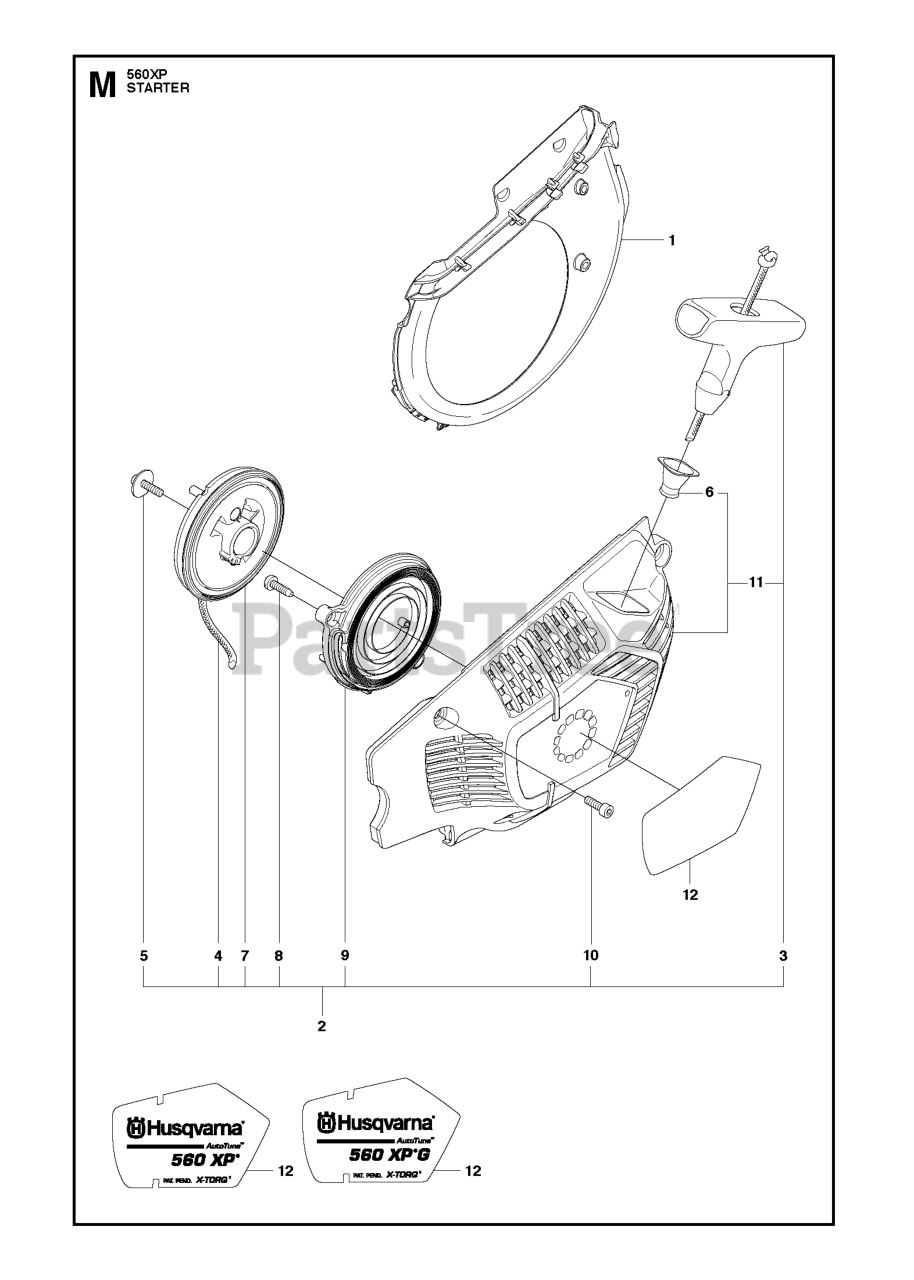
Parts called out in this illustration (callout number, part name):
1	COOLING AIR CONDUCTOR
2	STARTER ASSY
3	HANDLE
4	STARTER ROPE
5	SCREW
6	SLEEVE
7	STARTER PULLEY ASSY
8	SCREW
9	SPRING CASSETTE ASSY
10	SCREW.CIHPANMO M5X19 10.9
11	STARTER HOUSING
12	LABEL XP
12	LABEL XPG
